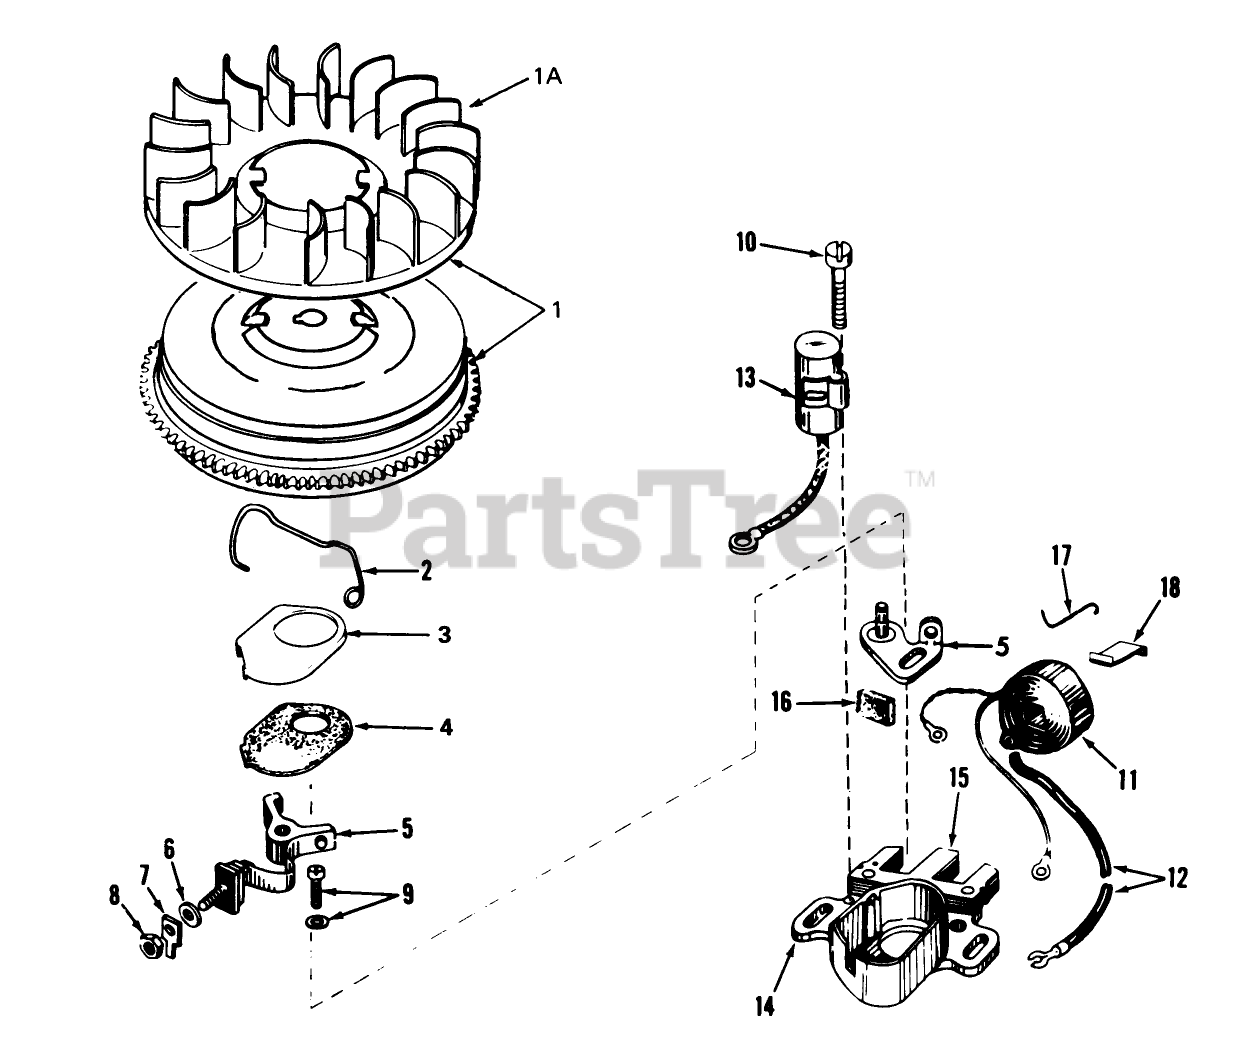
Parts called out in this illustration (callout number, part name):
1	Flywheel (Incl. No. 1A)
1A	Fan
2	Spring Breaker Box
3	Cover-Dust
4	Gasket, Dust Cover
5	Breaker Assy.
6	Washer
7	Terminal, Ground
8	DECAL
9	Breaker Screw
10	Condenser Screw
11	Coil Assy. (Incl. No. 12)
12	Wire, Lead
13	Condenser
14	Core & Plate
15	Stator Assy. (Incl. Nos. 2 thru 14, 16, 17 & 18)
16	Felt,Cam Wiper
17	Clip, Coil
18	Spring Coil Wedge
